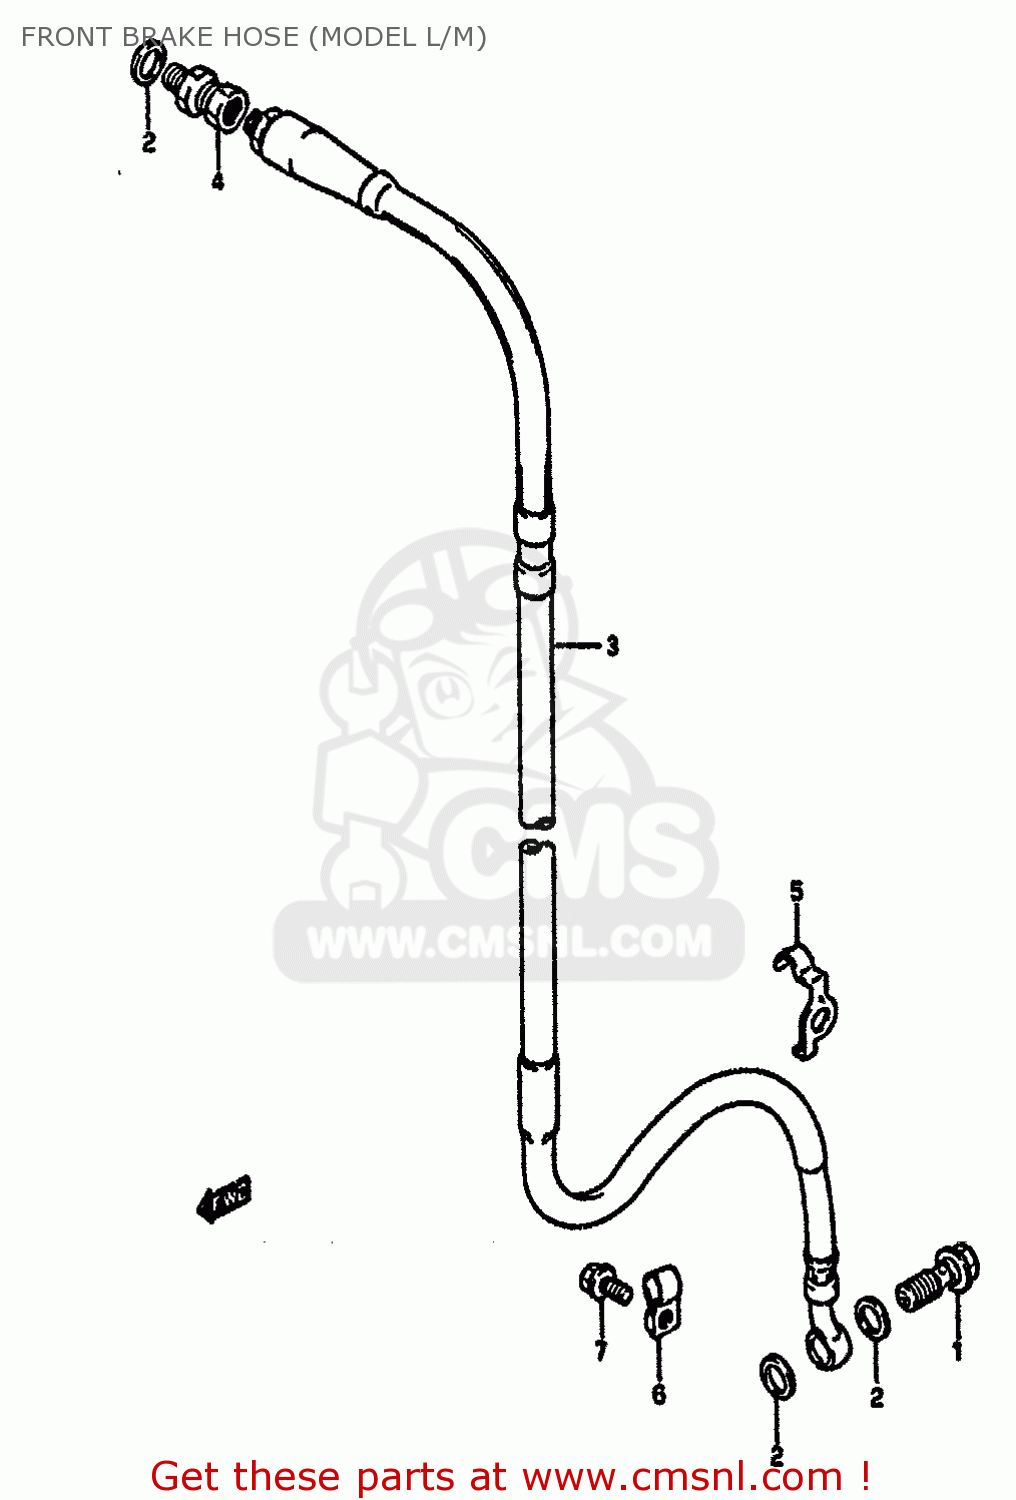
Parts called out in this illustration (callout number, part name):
1	BOLT UNION
2	WASHER(10X15X1.5)
3	HOSE,FRONT BRAKE
4	ADAPTOR,BRAKE HOSE
5	CLAMP,FRONT BRAKE HOSE
6	CLAMP,FR BRAKE HOSE NO.2
7	BOLT
